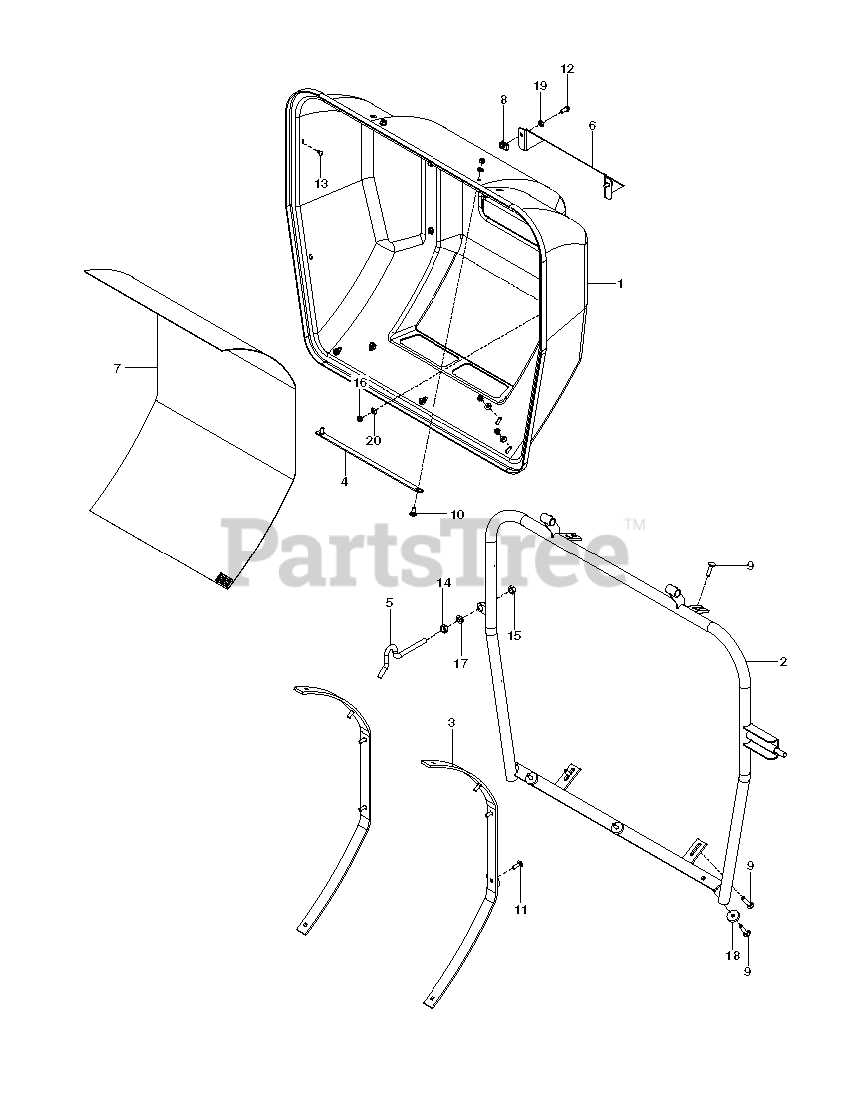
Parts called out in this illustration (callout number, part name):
1	CLAM SHELL (BACK)
2	REAR FRAME WLDT.
5	HOOK LATCH
6	CLAMSHELL VENT
7	SCREEN.VENT
8	CLIP NUT 5/16-18
9	BOLT, CARRIAGE 5/16X1-1/4
10	BOLT 5/16C X 3/4" CARRIAGE
11	RHSSNB 5/16C X 1.0
12	SCREW 5/16C X 1 HEX CAP
13	LARGE DOME RIVET
14	NUT, 1/2-13 THIN PROF NYL
15	NUT 1/2 HEX JAM
16	NUT 5/16 NYLOC
17	WASHER 1/2" SPLIT LOCK
18	WASHER NYLON
19	FLAT WASHER 5/16 SAE
20	WASHER 5/16 FLAT
